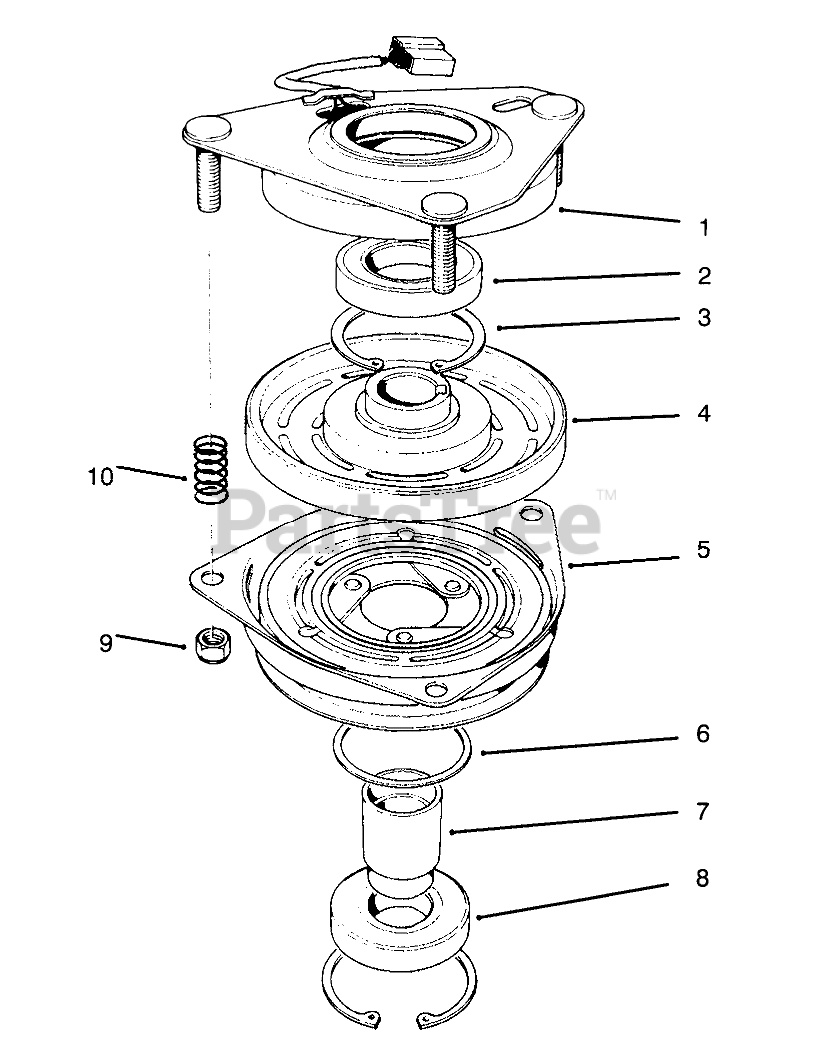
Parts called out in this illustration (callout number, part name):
1	Field Assembly(Incl Ref. #2, 3)
2	BEARING-FIELD
3	RING-RETAINING
4	Field Coil, Rotor & Bearing(Incl Ref. #1)
5	Armature & Pulley Assembly(Incl Ref. #3, 6, 7, 8)
6	SPACER-BEARING, PULLEY
7	COLLAR-BEARING
8	BEARING-PULLEY
9	NUT-LOCK
10	SPRING
